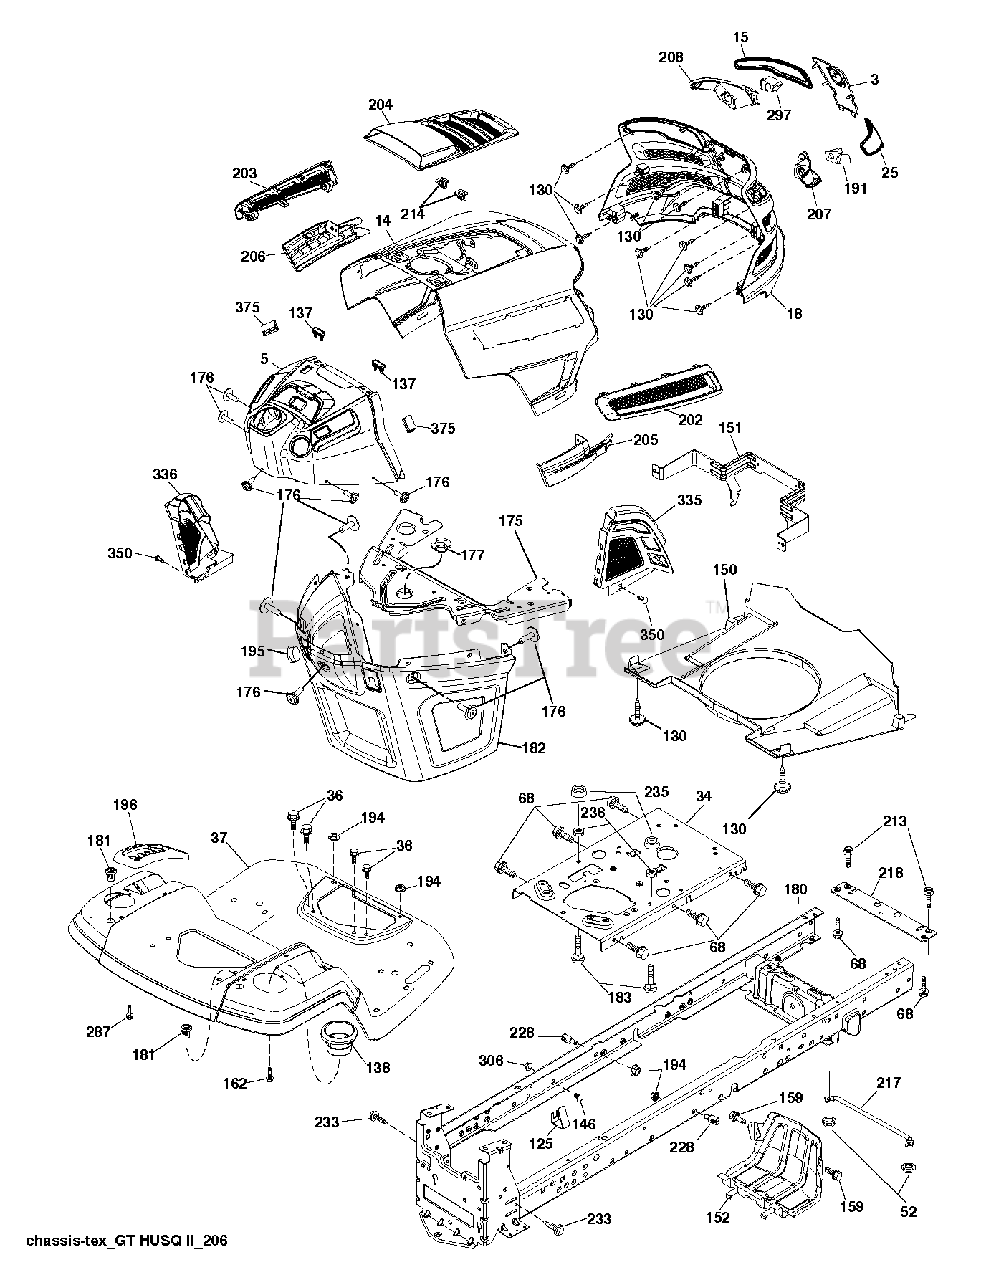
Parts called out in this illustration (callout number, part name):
3	APPLIQUE.SUBASM.GT.HUSQ.II
5	UPPER.GT2.SVC.MINDING.PTO.H.
14	HOOD.ASM.HUSQVARNA.GT.TEX.ORAN
15	LENS.HEADLIGHT.LH.GTII.2011
18	GRILLE.SUBSTRATE.2011.
25	LENS.HEADLIGHT.RH.GTII.2011
34	PLATE.ENGINE.WELDED.CHASSIS
36	SCREW 5/16"
37	FENDER.TLT.PDL.CNTRL.W/CPH.ORG
52	LOCKNUT
68	SCR 5/16-18 X 1/2 SELFTAP ZN
125	CLIP.FUEL.LINE
130	SCREW.#10 X 0.750.BOS
137	BUMPER DASH
138	HOLDER.CUP.LT.GREY
146	BOLT.RDHD.SHT.SQNK.3/8-16X5/8
150	AIR.DUCT.GTV.BLACK
151	BRACKET.PIVOT.HOOD.GT.HUSQ.II
152	SHIELD.BROWNING.PNT.GT.V2
159	SCREW, 3/8-16X3/4
162	SCREW.HI-LO.CONSOLE
175	Crossmember Plate
176	SCREW.#10-24X5/8.RN.QU
177	BUSHING STEERING
180	CHASSIS
181	BUSHING.MNT.FEND.CRGO.TEX.49
182	DASH.LOWER.COMMON.12V.ADAPTOR
183	BOLT.5/16-18X1-1/4 FULL THD
191	INSERT.REFLECTIVE.RH.HUSQ.GTII
194	NUT LOCK HEX FLANGE 5/16-18
195	PLUG.HOLE.DASH.LOWER.12V.BLK
196	DECKLFT.CONSOL FULL ASSM GREY
202	VENT.SIDE.RH.GT.HUSQ.II.
203	VENT.SIDE.LH.GT.HUSQ.II.498
204	VENT.TOP.HUSQ.GT2
205	SIDE.TRIM.RH.GT.HUSQ.II
206	SIDE.TRIM.LH.GT.HUSQ.II.GRAY
207	BEZEL LIGHT.RH.GT.II.MYLAR
208	BEZEL LIGHT.LH.GT.II.MYLAR
213	BOLT
214	CLIP.RETAINER.TINNER.
217	ROD.PIVOT.HOOD
218	X-PIECE.HOOD.STOP.NON/
228	STUD.FASTNER.W/ANTI-ROTATE
233	BOLT.SHOULDER
235	SPACER FENDER
236	NUT.CENTERLOCK.5/16-
287	SCREW 1/4X20
297	INSERT.REFLECTIVE.LH.HUSQ.GTII
306	NUT LOCK FLG 3/8-16 UNC
335	COVER.LOWER.DASH.RH.BLACK
336	COVER-LH.LOWER.DASH.GT2.BLACK
350	CLIP.X-MAS.TREE
375	BUMPER CLIP-ON. DASH 1"
